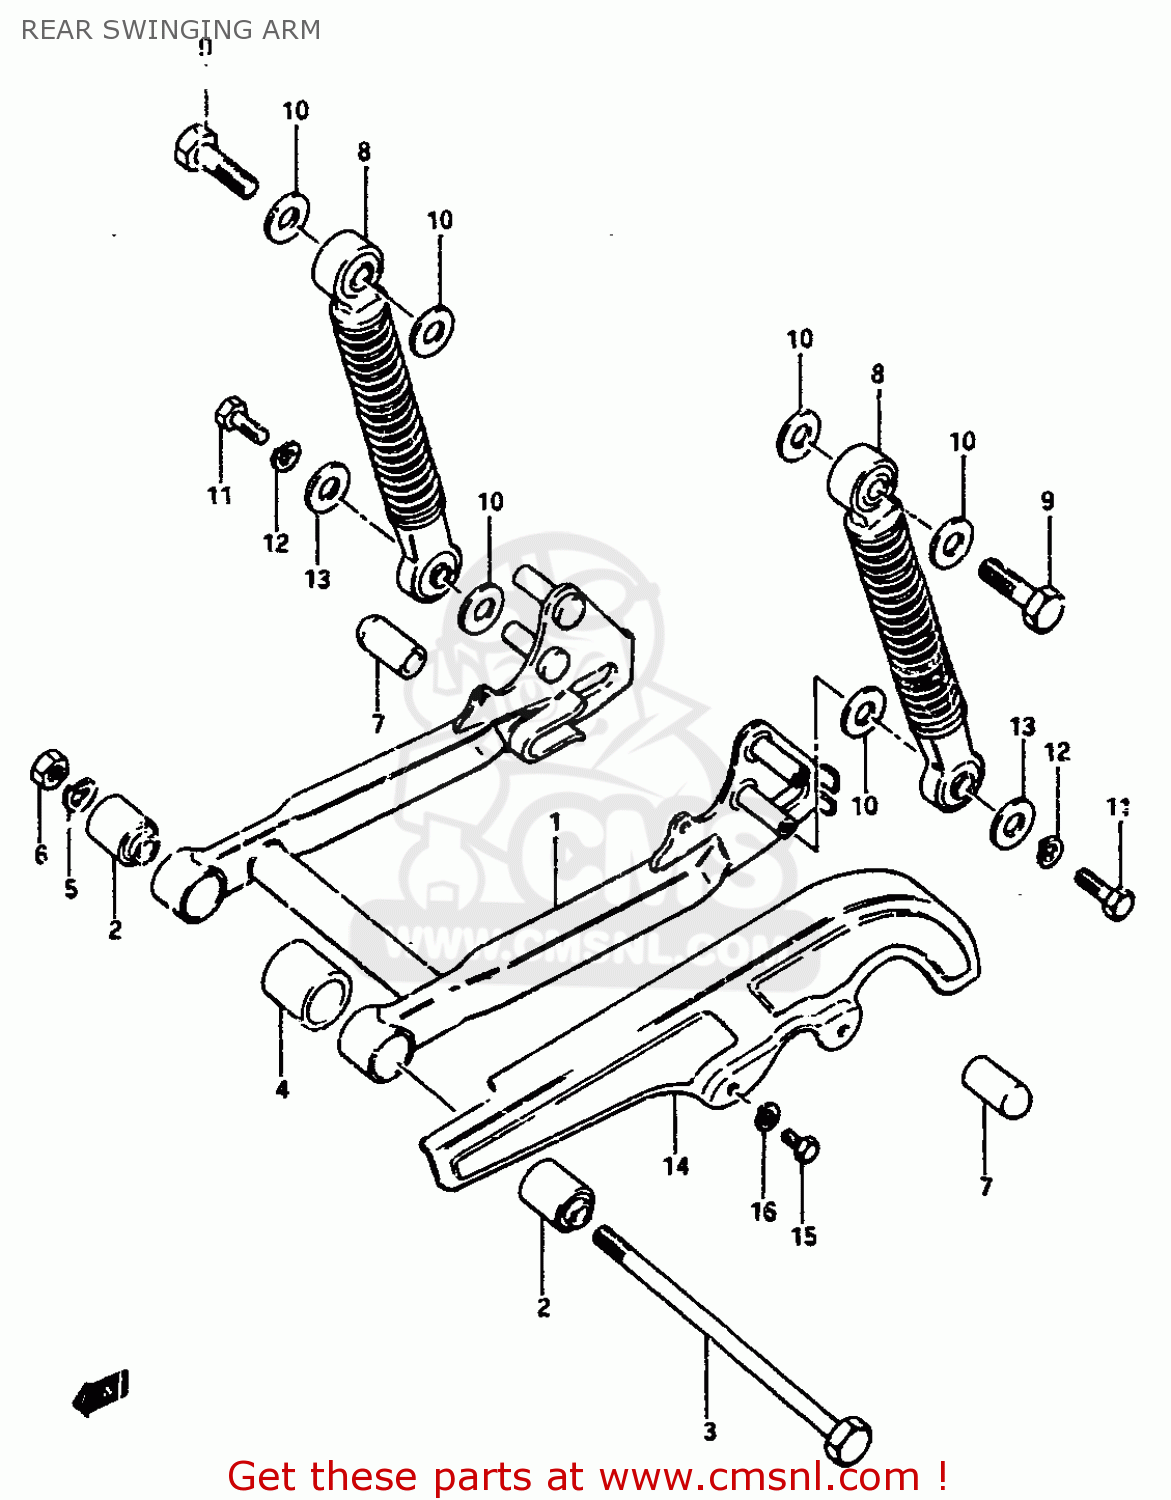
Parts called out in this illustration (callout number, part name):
1	ARM,REAR SWING
2	BUSH
3	SHAFT,RR SWINGINGARM PIVOT
4	CUSHION
5	WASHER,LOCK,10
6	NUT
7	CAP,RR SHOCK ABSORBER BOSS
8	ABSORBER ASSY,RR SHOCK
9	BOLT,M10X1.25X
10	WASHER
11	BOLT
12	WASHER,LOCK
13	WASHER (6.5X24X1.6)
14	CASE,CHAIN
15	BOLT
16	WASHER,LOCK
